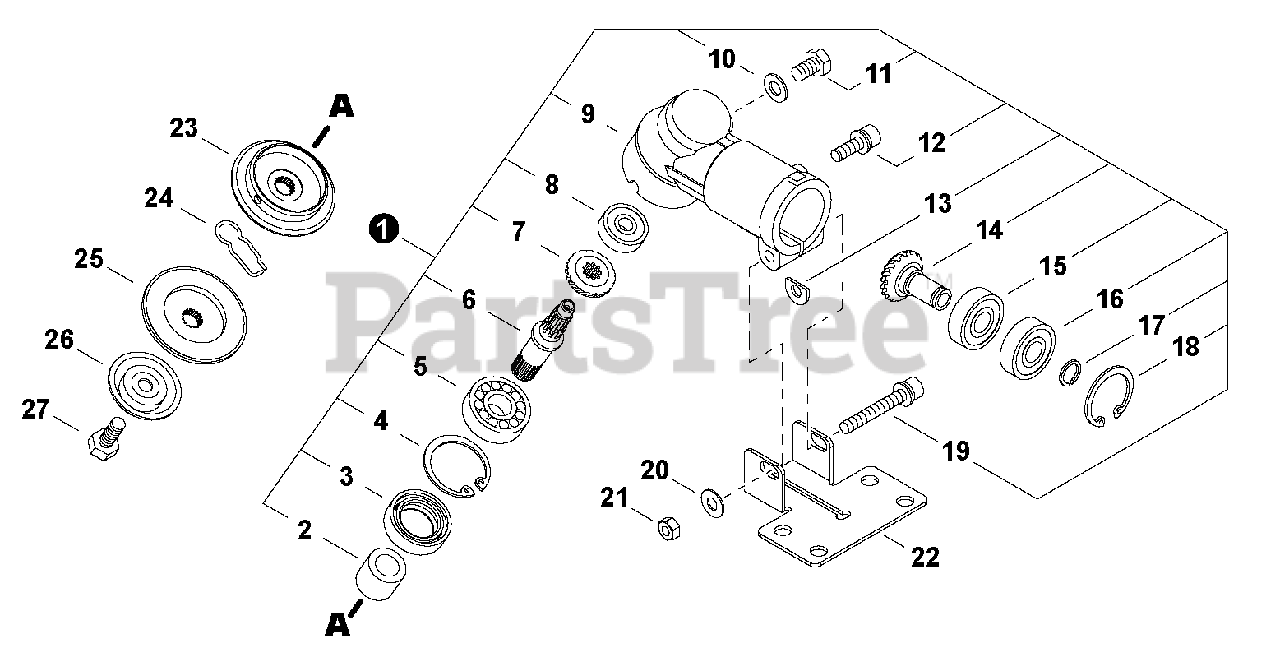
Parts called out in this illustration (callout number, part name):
1	GEAR CASE ASSY
3	SEAL, OIL
4	RING, SNAP Ø32
5	BEARING, BALL 6201
6	SHAFT, GEAR
7	GEAR, BEVEL
8	BEARING, BALL
9	CASE, GEAR
11	BOLT M6×10
12	BOLT M5×16
13	D-WASHER
14	GEAR, PINION
15	BEARING, BALL 6901
16	BEARING, BALL 6901ZZ
17	RING, SNAP Ø12
18	RING, SNAP Ø24
19	BOLT M6×40
20	WASHER 6.5×13×1
21	NUT, HEX M6
22	PLATE, SHIELD MOUNTING
23	PLATE, ADAPTOR - UPPER
24	CLIP, BLADE
25	PLATE, ADAPTOR - LOWER
26	GUARD, BOLT
